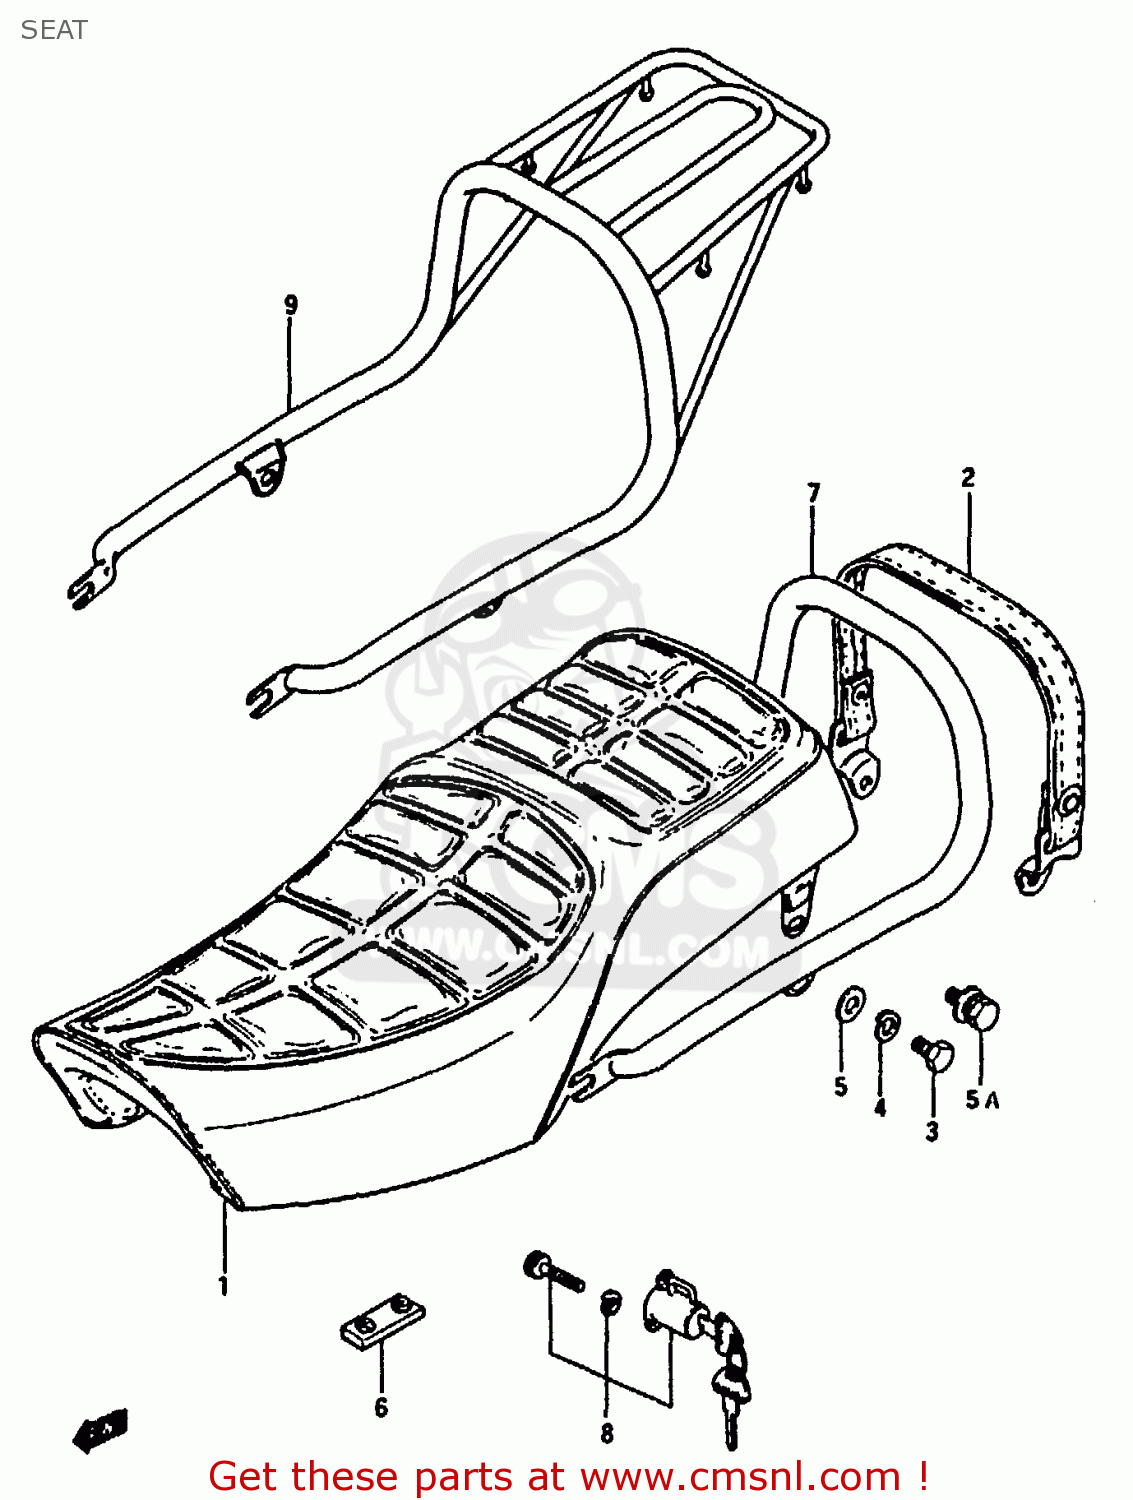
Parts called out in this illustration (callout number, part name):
1	SEAT ASSEMBLY
2	BAND,SEAT GRIP
3	BOLT
4	LOCK WASHER
5	WASHER
5A	BOLT
6	CUSHION
7	HANDLE,PILLION RIDER
8	LOCK SET,HELMET
9	CARRIER
